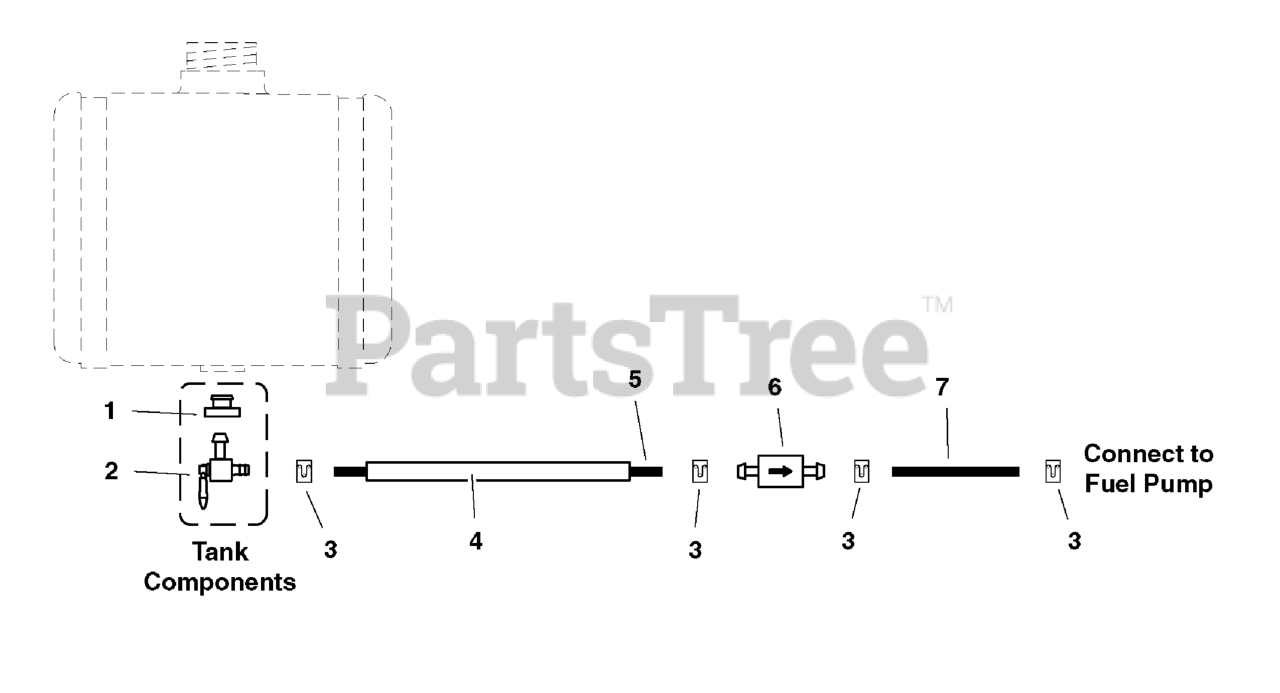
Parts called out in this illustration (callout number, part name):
1	BUSHING-FUEL TANK RED RUBBER
2	FUEL SHUTOFF VALVE
3	CLAMP, Hose
4	WIRE LOOM, 35"
5	1/4" Fuel Line, 37" Long
6	FUEL FILTER
7	HOSE, 1/4" FUEL, 9.00"
